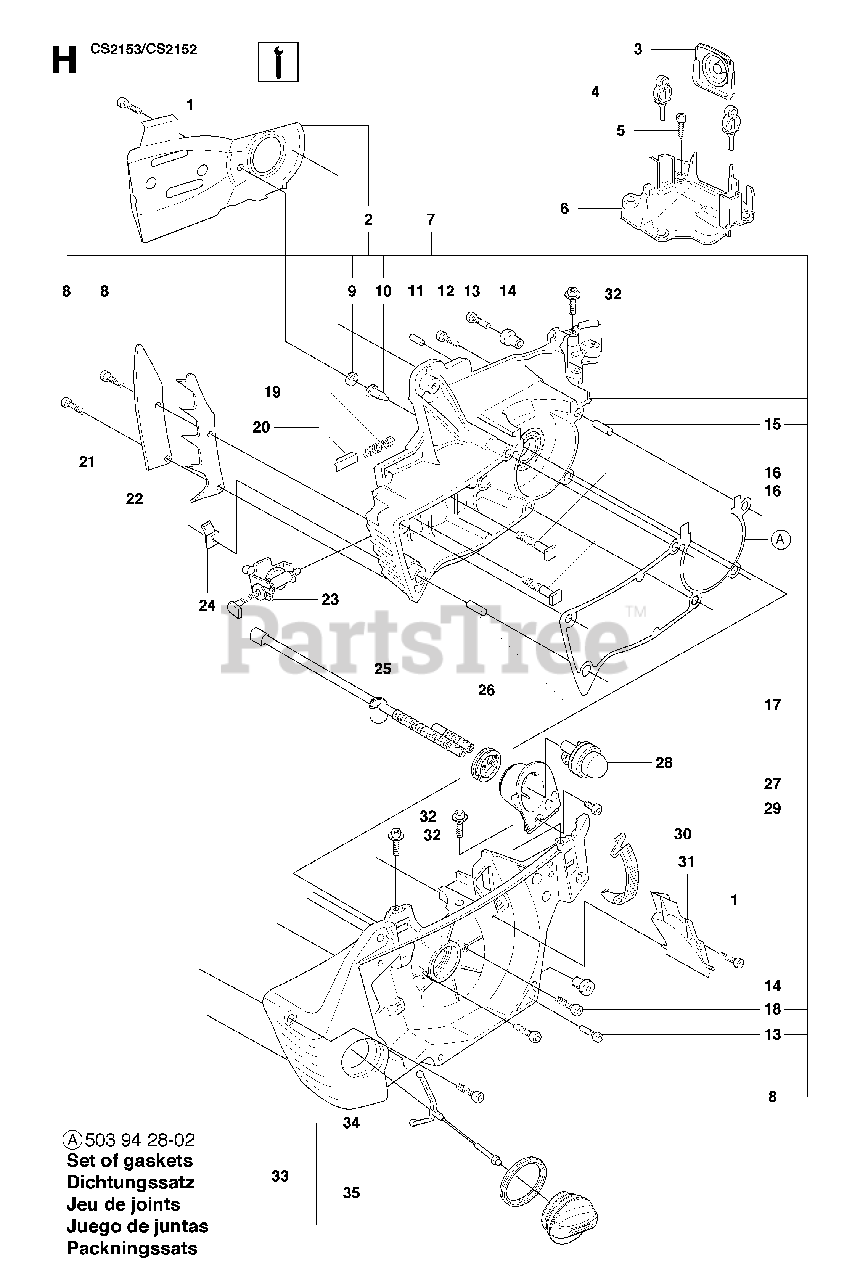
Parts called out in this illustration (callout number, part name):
2	CHAIN GUIDE PLATE
6	CARBURETOR AREA BASE
7	CRANKCASE ASSY
9	PLUG
10	VALVE-CHECK (DUCKBILL)
14	MOVEMENT LIMITER
19	LOCK SPRING
22	FELLING DOG
23	CHAIN TENSIONER
24	CHAIN CATCHER
25	RP HOSE
28	AIR PURGE BUBBLE
29	SCREW IHSCT
31	DEFLECTOR
35	OILCAP GASKET
A	GASKET SET
